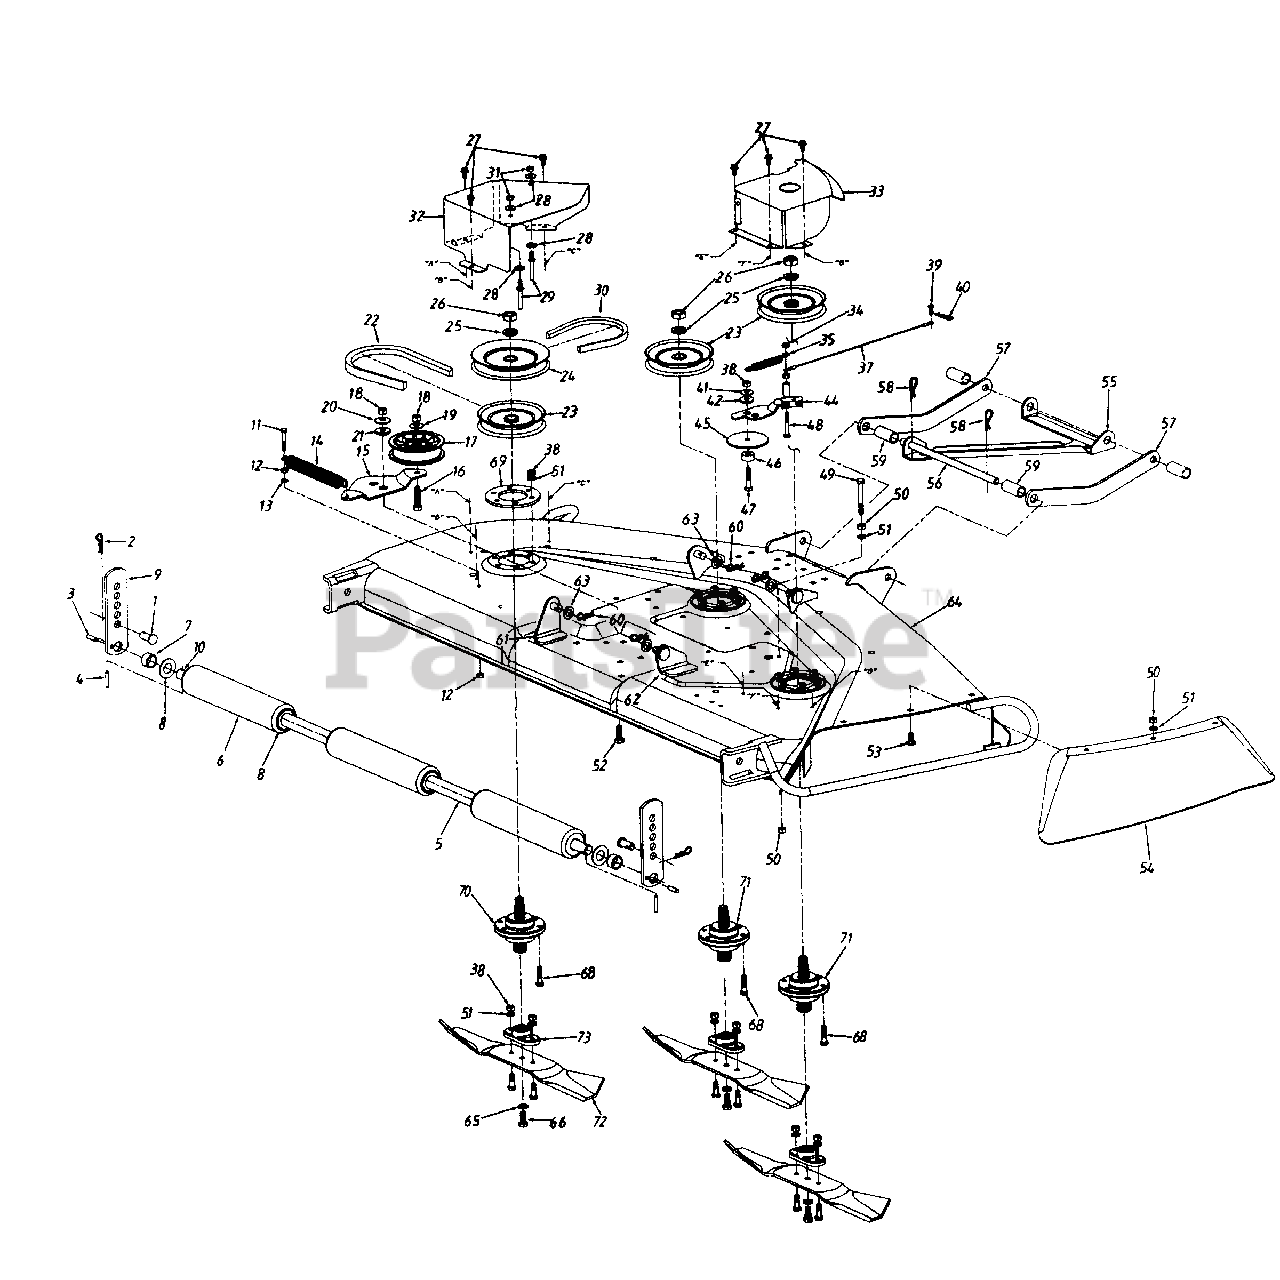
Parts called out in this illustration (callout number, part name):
1	Clevis Pin
2	Hairpin Clip
3	Spring Pin 1/4" x 1" Lg.
4	Spring Pin 3/16" x 1-1/4" Lg.
7	Spacer .75" I.D.
8	Fl-Wash. .76" I.D. x 1.5" O.D.
10	Roller Shaft
11	Hex Bolt 1/4-28 x 1.5" Lg. (Gr. 5)
12	Hex Nut 1/4-28 Thd.
13	L-Wash. 1/4" I.D.
14	Ext. Spring 7.33" Lg.
17	Idler Pulley
18	Hex Nut 3/8-24 Thd.
19	Bell-Wash. 3/8" I.D.
20	Bell-Wash. .39" I.D. x 1.13" O.D.
21	Shld. Spacer .625" I.D.
22	"V"-Belt
23	Deck Pulley
24	Upper Deck Pulley
25	L-Wash. 5/8" I.D.
26	Hex Jam Nut 5/8-18 Thd.
27	Hex Wash. Hd. Scr. 1/4-20 x .5" Lg.
28	Bell-Wash. 1/4" I.D.
29	Belt Guard Pin
30	"V"-Belt
31	Hex Nut 1/4-20 Thd.
35	Ext. Spring 3.97" Lg.
37	Brake Cable
38	Hex Nut 5/16-24 Thd.
39	Clevis Pin
40	Hairpin Clip
41	Bell-Wash. .325" I.D.
42	Shld. Spacer
44	Brake Ass'y
45	Fl-Wash. 5/16" I.D. x .3" O.D
46	Spacer .44" Lg.
48	Hex Bolt 1/4-28 x 1.75" Lg. (Gr. 5)
49	Hex Bolt 5/16-18 x 2.5" Lg
50	Hex Nut 5/16-18 Thd.
51	L-Wash 5/16" I.D.
52	Hex Bolt 3/8-24 x 1" Lg.
53	Carr. Bolt 5/16-18 x .75" Lg.
59	Spacer 1.75" Lg.
60	Hairpin Clip
63	Fl-Wash. 1/2" I.D. x .93" O.D.
66	Hex Bolt 3/8-24 x .88" Lg. (Gr. 5)
68	Hex Bolt 5/16-24 x 1-1/4" Lg. (Gr. 5)
69	Spindle Reinforcement Plate
70	Spindle Ass'y. (L.H.)
71	Spindle Ass'y. (R.H. & Center)
72	Blade
73	Blade Adapter
